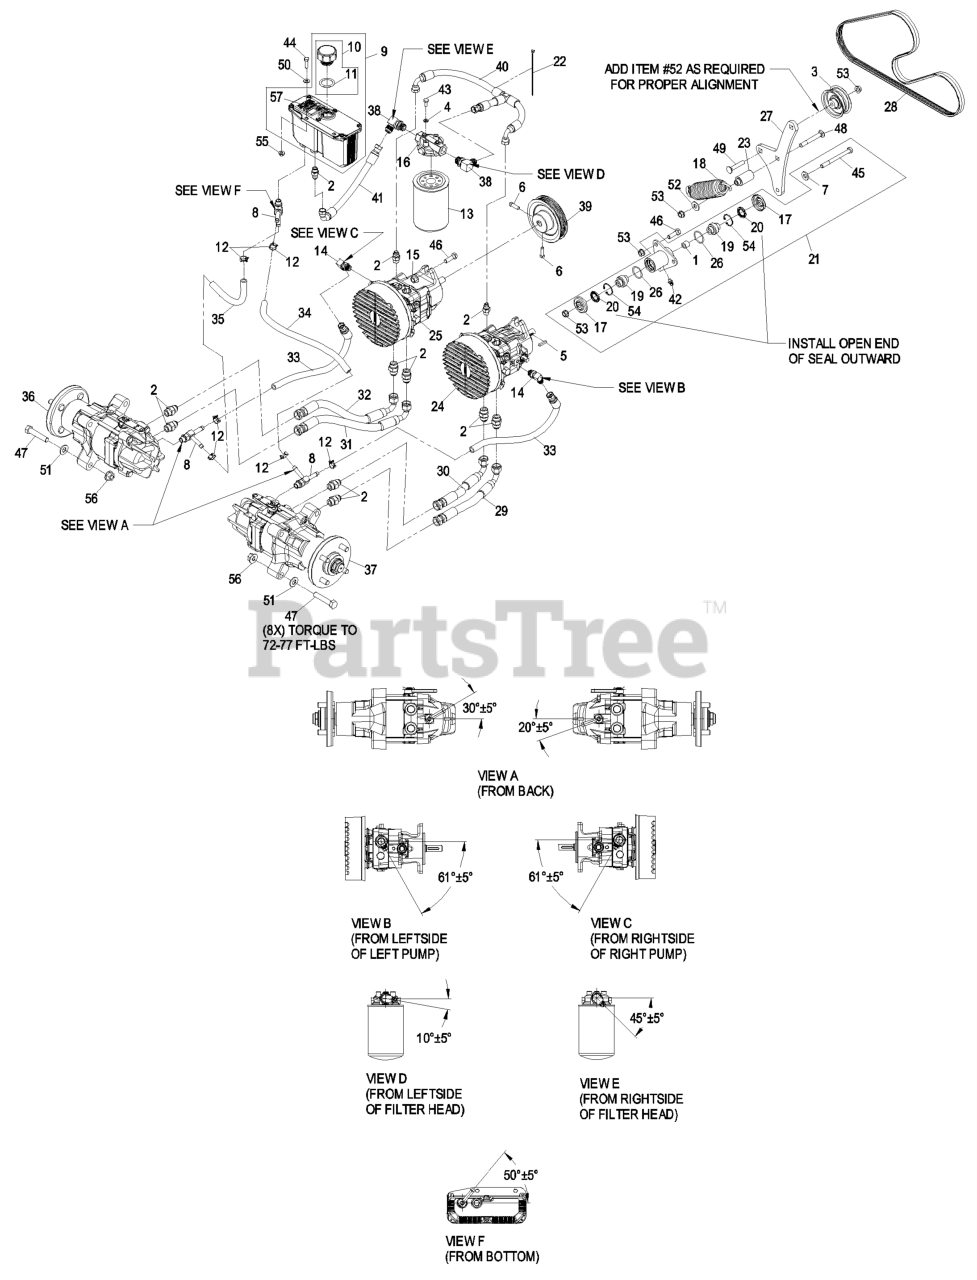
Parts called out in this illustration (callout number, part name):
1	BUSHING-LEVER, LIFT
2	FITTING-STRAIGHT
3	PULLEY-FLAT IDLER
4	WASHER-LOCK
6	SCREW-SET
7	WASHER-BELLEVILLE
8	ADAPTER-RUN, TEE
9	HYDRAULIC TANK ASM
10	KIT,HYD RES CAP W/GASKET
11	GASKET-CAP
12	CLAMP-HOSE
13	FILTER,XP HYD 25 MICRON
14	FITTING-90 DEG
15	NUT-FLANGE
16	HEAD-FILTER
17	GUARD-TOP
19	BEARING-SPHERICAL
20	SEAL-LIP, SINGLE
21	KIT,'04 XP PUMP IDLER
22	TIE-CABLE
23	SPACER, SPRING 1.75 (PLAT
24	PUMP,HYDRO PR W/FAN LH
25	PUMP,HYDRO PR W/FAN RH
28	BELT,5K EL-54.50
29	HOSE,HYDRAULIC LH LOWER
30	HOSE,HYDRAULIC LH UPPER
31	HOSE,HYDRAULIC RH LOWER
32	HOSE,HYDRAULIC RH UPPER
33	ASM,CASE DRAIN
34	HOSE,CASE DRAIN LH
35	HOSE,CASE DRAIN RH
37	MOTOR,PRM20-LH
38	FITTING-90 DEG
40	ASM,CHARGE HOSE TEE PR
41	ASM,CHARGE HOSE PR
42	FITTING-GREASE, 90 DEG
43	SCREW-HH
44	SCREW-HH
45	SCREW-HH
46	SCREW-HH
47	SCREW-HH
48	SCREW-CARR
49	SCREW-HH
50	WASHER-FLAT
51	WASHER-FLAT
52	WASHER-FLAT
53	NUT-HHF, WHIZ
54	RING-SNAP
56	NUT-HHF
